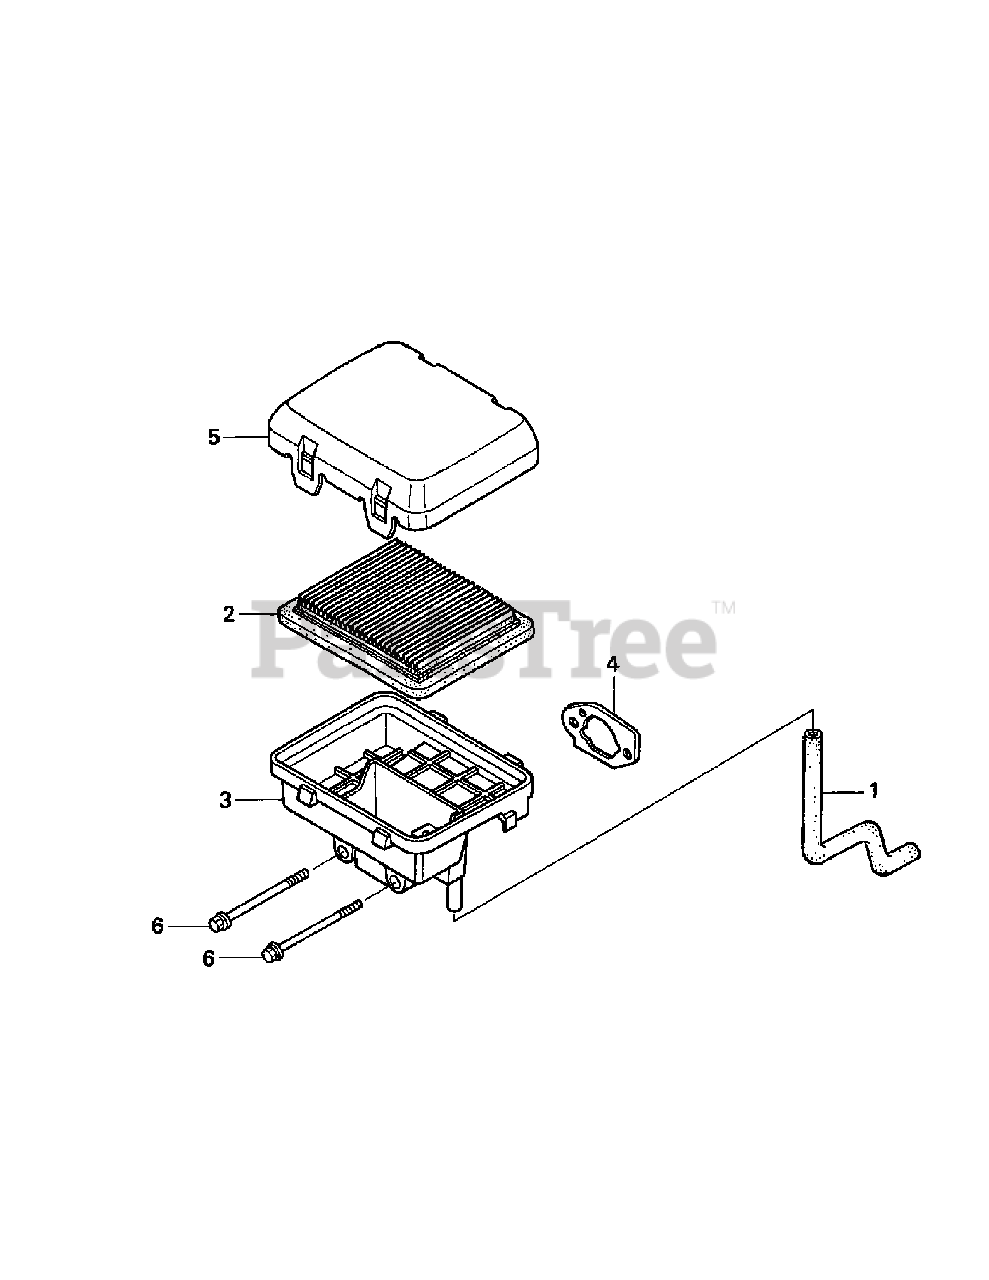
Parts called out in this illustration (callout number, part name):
1	Breather Tube
2	Air Cleaner Element
3	Air Cleaner Housing
4	Air Cleaner Gasket
5	Air Cleaner Cover
6	Flange Bolt, 6 x 112
